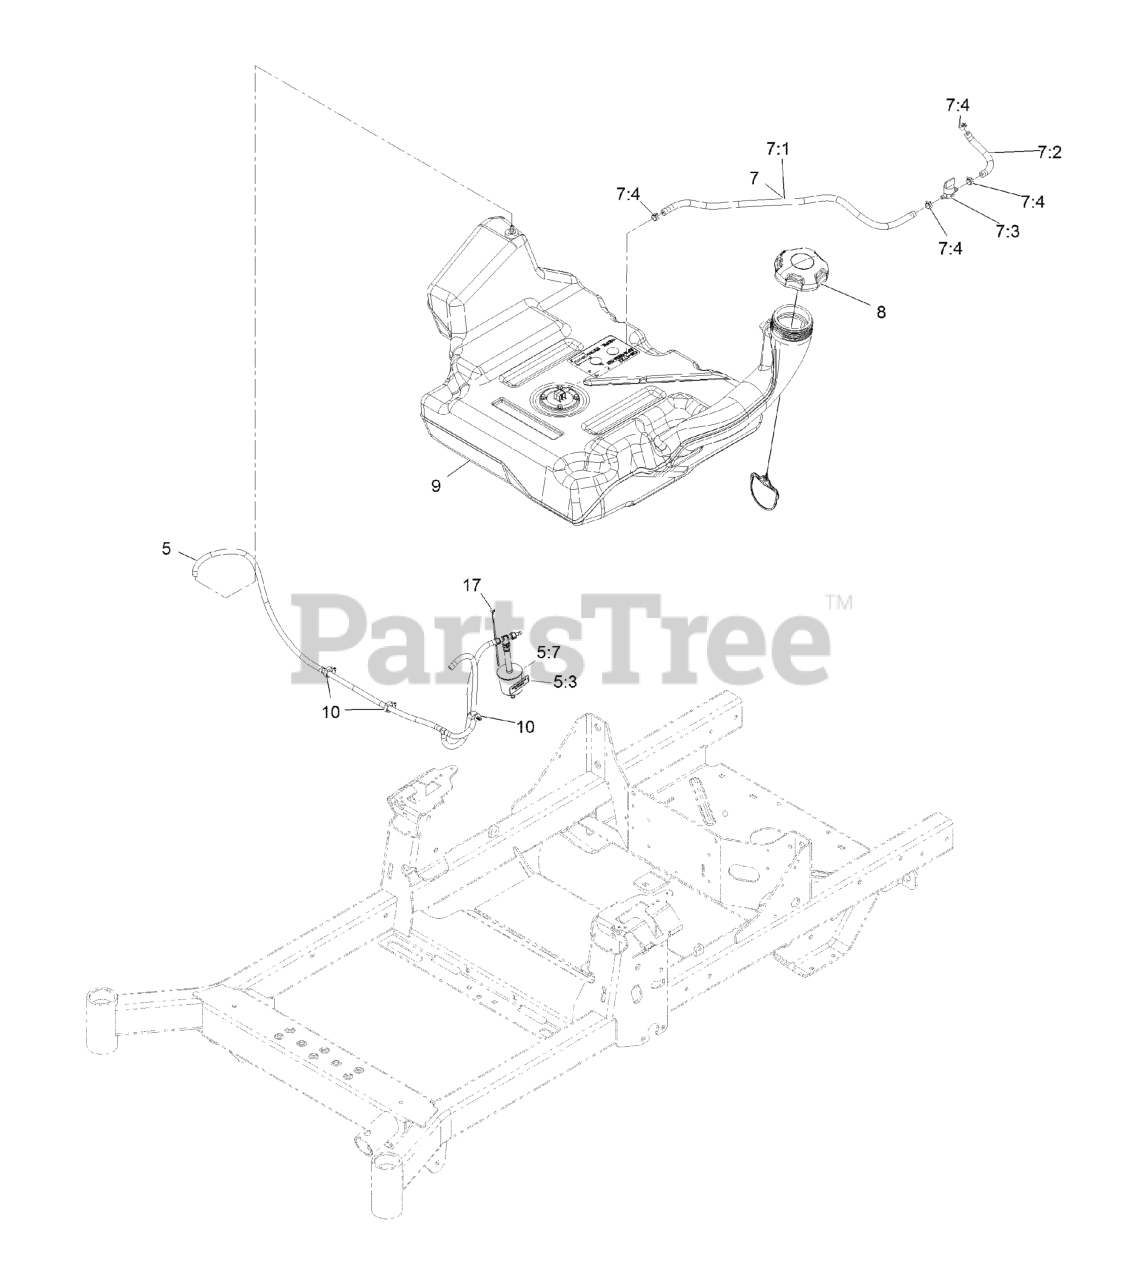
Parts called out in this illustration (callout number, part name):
5	VENT HOSE ASM
5:3	DECAL-FILTER, EMISSIONS
5:7	FILTER-FUEL
7	FUEL HOSE ASM
7:1	HOSE-FUEL
7:2	HOSE-FUEL
7:3	VALVE-FUEL
7:4	CLAMP-HOSE
8	CAP-FUEL, RATCHETING
9	TANK-FUEL
17	TIE-CABLE
